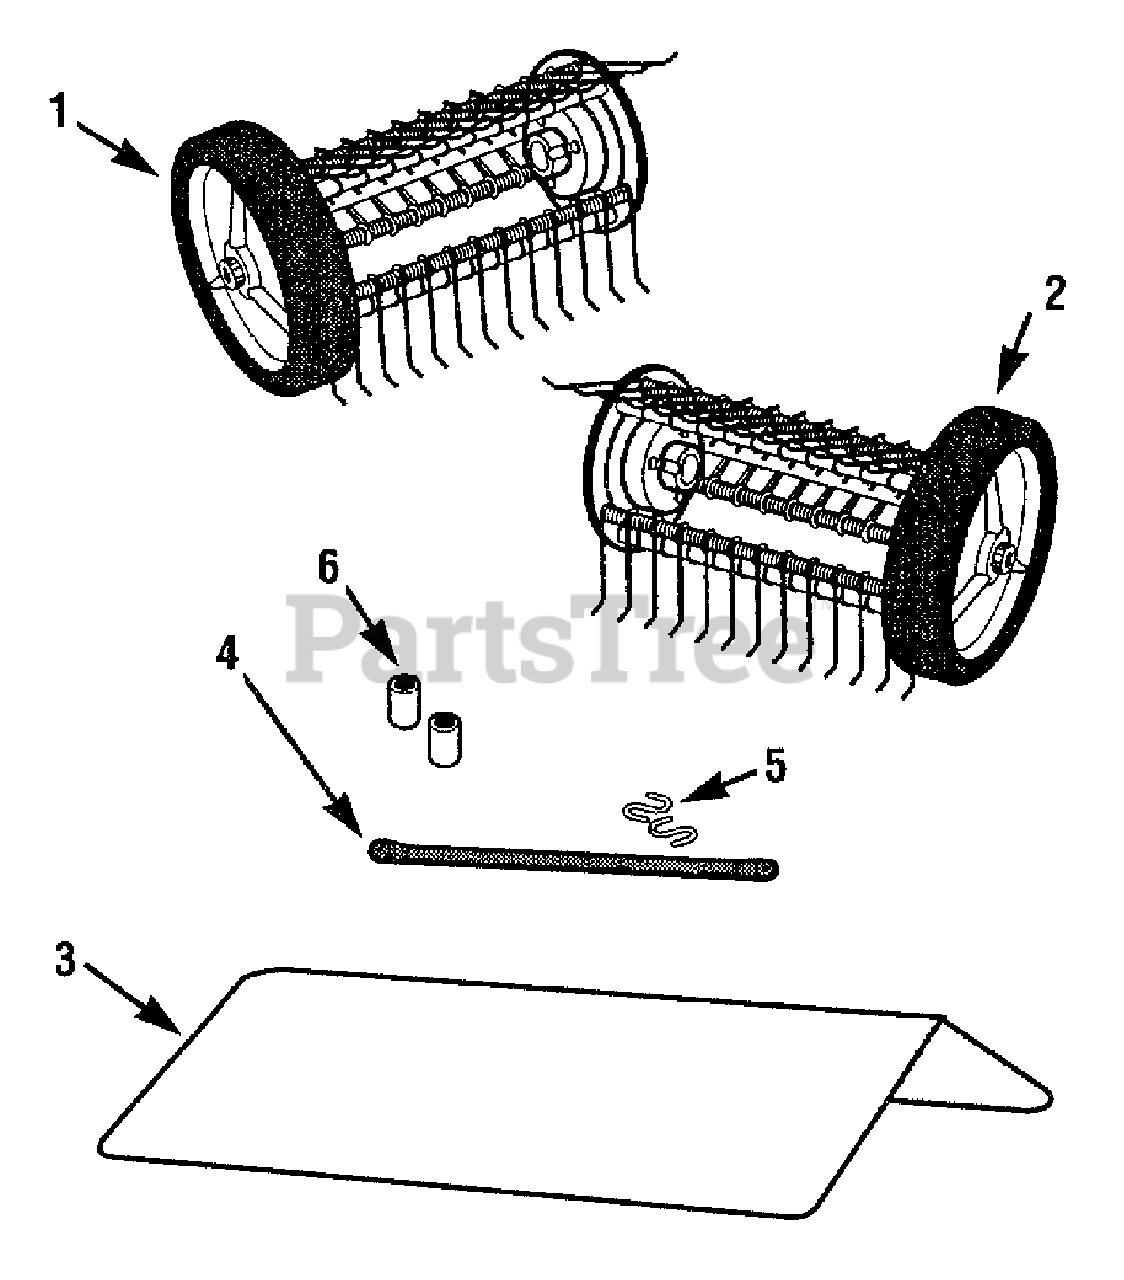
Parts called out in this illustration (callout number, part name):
1	Rake Assembly - left side
2	Rake Assembly - right side
3	Debris Shield
4	Mounting Strap
6	1-1/4"long Spacer
